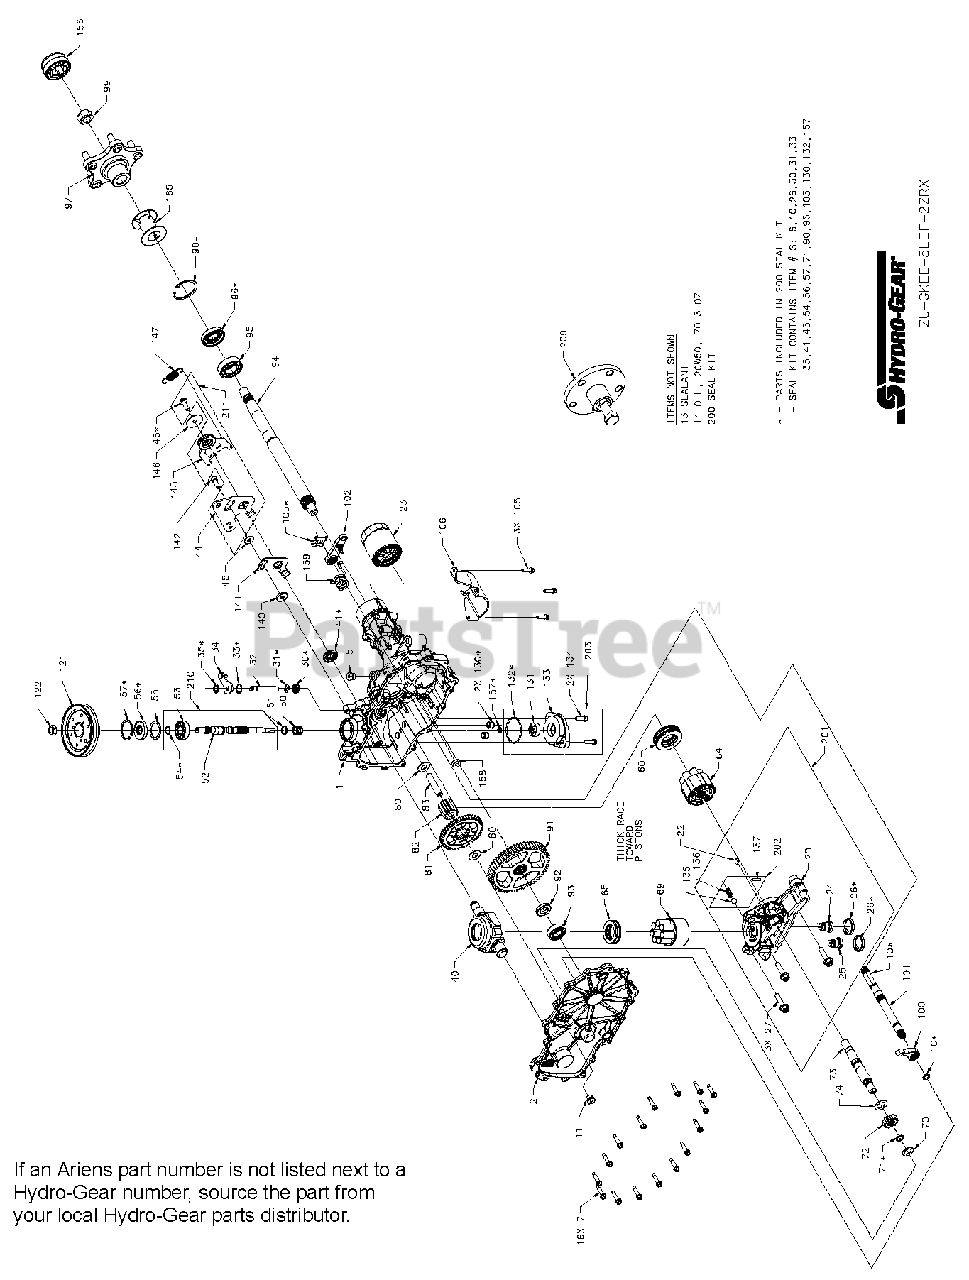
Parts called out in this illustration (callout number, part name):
13	SEALANT
23	FILTER, OIL
30	SEAL, LIP .375 x .75 x .25
31	RING, RET .375 EXTRNL
35	RING, RTNG .375 EXT
40	TRUNNION, SWASHPLATE
41	SEAL, LIP 12 x 32 x 7
46	TWHCS 5/16-24 x 1.00 (PATCH)
51	WASHER-FLAT .59 x .79 x .04
55	WASHER 1.23 x 1.56 x .04
56	SEAL, LIP 17 x 40 x 7
57	RING, RETAINING
80	WASHER .5 x 1.0 x .03
95	BRG, BALL 25.4 x 52 x 15
96	SEAL, LIP 1.000 x 2.049 x .375
99	NUT, HEX LOCK 3/4-16
122	NUT,HEX JAM 1/2-20 W/ PATCH
132	O-RING, -137, 0.103 x 2.050
146	WASHER, .343 x 1.500 x .062
147	SPRING, EXTNSN RTN-34LBS
157	SEAL, LIP 8 x 12 x 3 VC
